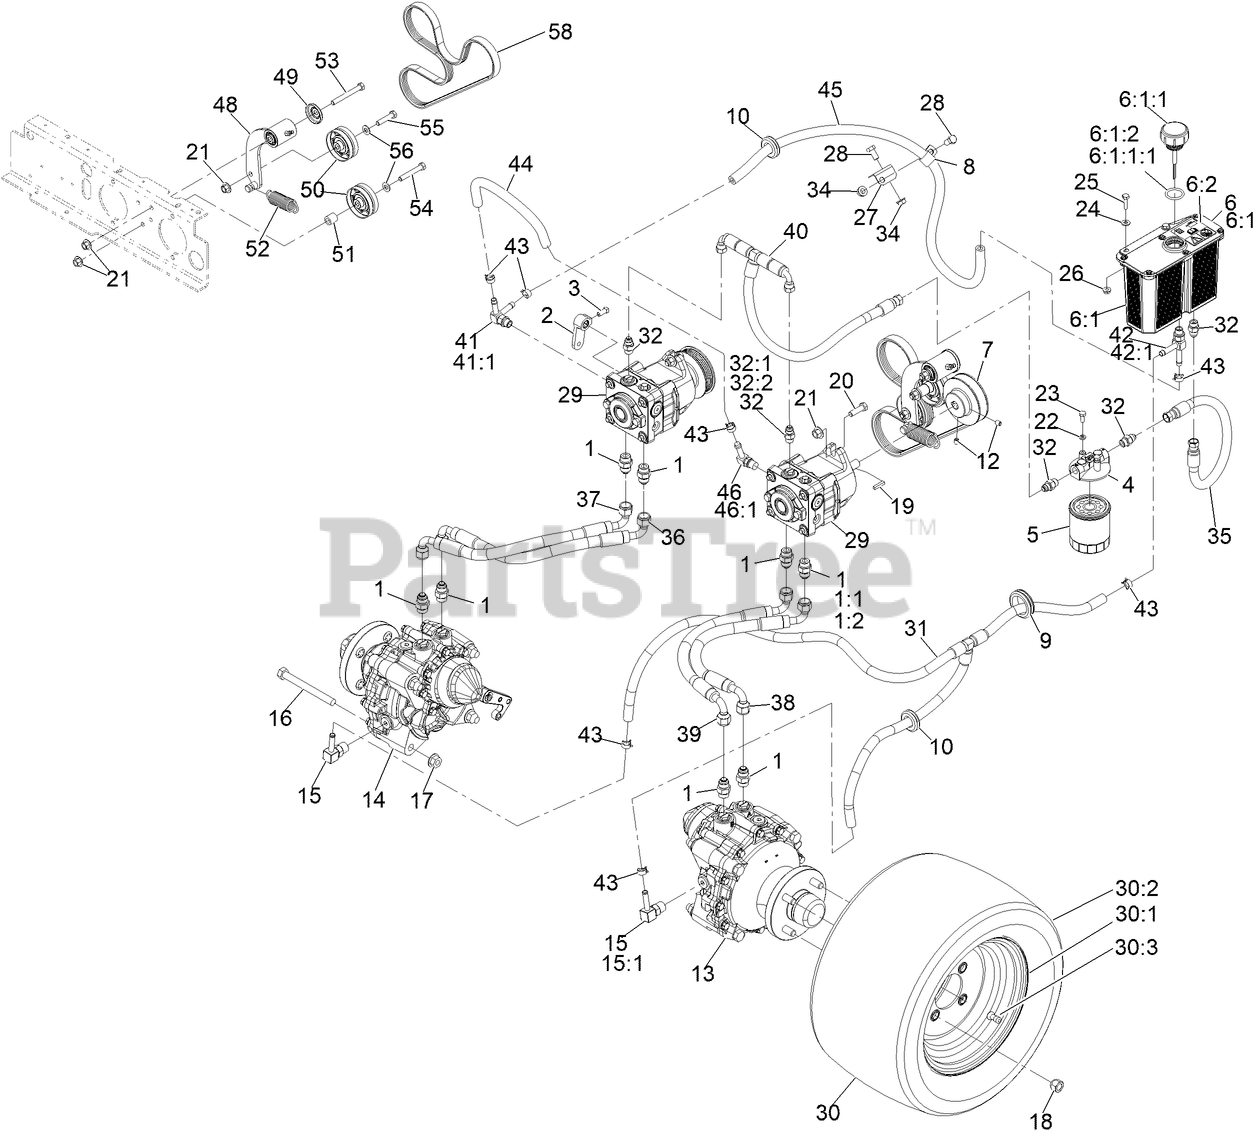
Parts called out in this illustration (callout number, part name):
1	FITTING-STRAIGHT
1:1	O-RING
1:2	O-RING
2	ARM-CONTROL, PUMP
3	SCREW-SET, SQH
4	HEAD-FILTER
5	ELEMENT-FILTER, 25 MICRON
6	RESERVOIR ASM
6:1	Reservoir-HYD
6:1:1	RESERVOIR CAP ASM
6:1:1:1	O-RING
6:1:2	O-RING
6:2	DECAL-WARNING
7	SHEAVE
8	CLIP-LOOM
9	GROMMET
10	GROMMET
12	SCREW-SET
13	MOTOR-HYD, LH
14	MOTOR-HYD, RH
15	FITTING-90
15:1	O-RING
16	SCREW-HH
17	NUT-HHF
18	NUT-LUG
20	SCREW-HH
21	NUT-FLANGE
22	WASHER-LOCK
23	SCREW-HH
24	WASHER-FLAT
25	SCREW-HH
26	NUT-HF
27	BRACKET-CLAMP
28	SCREW-HH
29	12CC HYDRO PUMP ASM
30	WHEEL AND TIRE ASM
31	HYDRAULIC HOSE ASM
32	FITTING-STRAIGHT
32:2	O-RING
34	NUT-HHF, WHIZ
35	HYDRAULIC HOSE ASM
36	HYDRAULIC HOSE ASM
37	HYDRAULIC HOSE ASM
38	HYDRAULIC HOSE ASM
39	HYDRAULIC HOSE ASM
40	HYDRAULIC HOSE ASM
41	ADAPTER-TEE
41:1	O-RING
42	ADAPTER-RUN, TEE
42:1	O-RING
43	CLAMP-HOSE
44	HOSE-HYD
45	HOSE-HYD
46	FITTING-ELBOW, 90
46:1	O-RING
48	IDLER ASM
49	GUARD-TOP
50	PULLEY
51	SPACER-MOUNTING, STEERING
52	SPRING-IDLER
53	SCREW-HH
54	SCREW-HH
55	SCREW-HH
56	WASHER-FLAT
58	BELT-V
